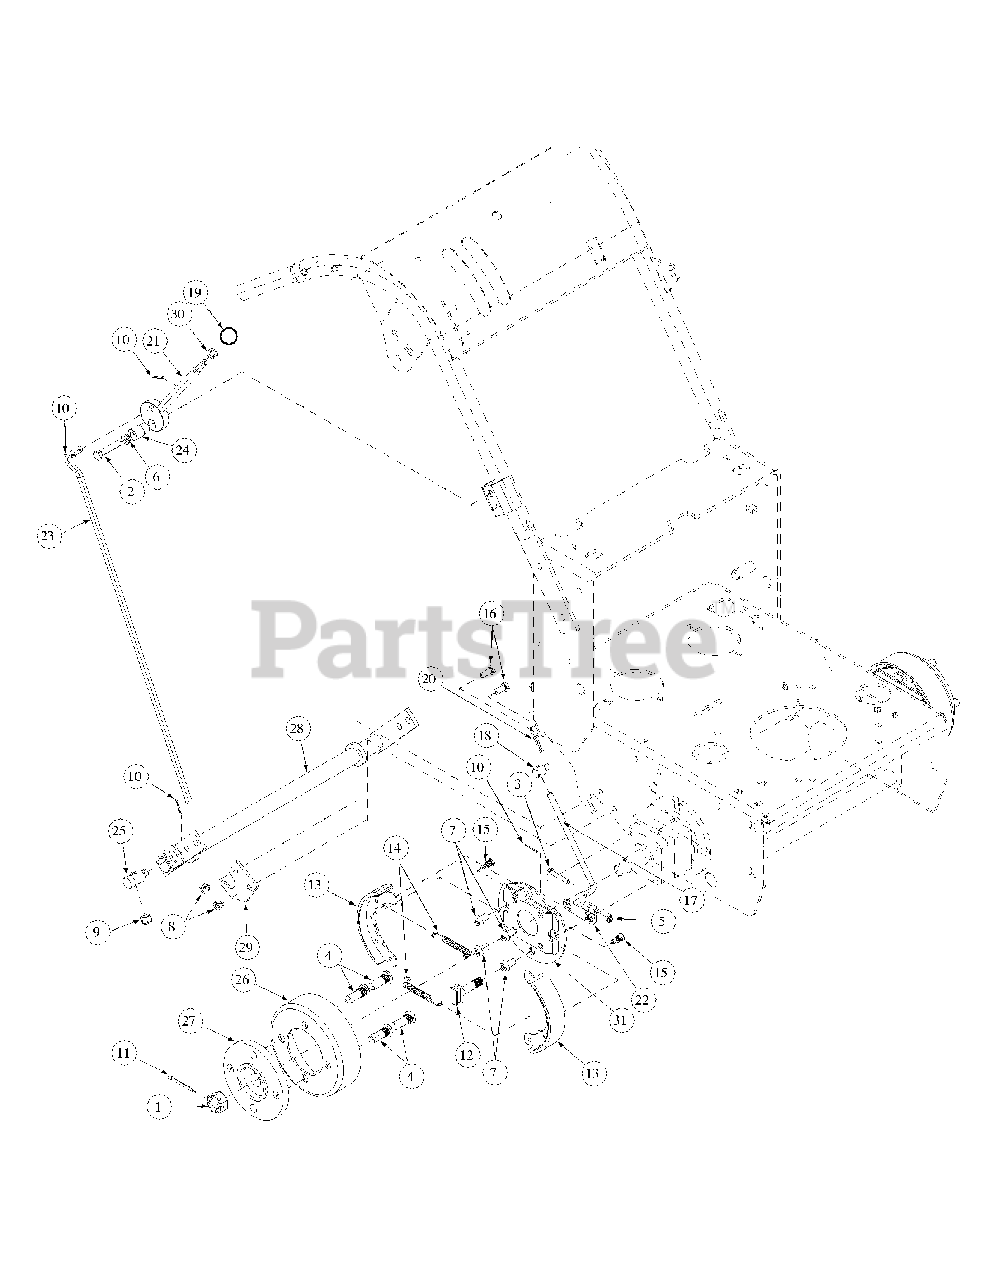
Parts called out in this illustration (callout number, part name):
1	Nut, Castle, 3/4-16
2	Capscrew, 3/8-16 x 1" Grade 5 Zinc
3	Cap Screw, 1/4-20 x 1.50, Grade 5
4	Bolt, Wheel, 1/2-20 x 1-3/8
5	Lock Nut, Nylon Insert, 1/4-20 Grade A
6	Lock Washer, 3/8 Zinc
7	Capscrew, Socket Button Hd., 3/8-16 x 3/4 Zinc
8	Nut, 5/16-18, Nylock
9	Nut, Nylon Insert, 3/8-16 Grade A
10	Cotter Pin, 3/32 x 3/4, Zinc
11	Cotter Pin, 5/32 x 1-1/2 Zinc
12	Brake Cam, Actuating
13	Brake Shoe w/Lining, 6 x 1-1/4
14	Brake Spring, Tension
15	Brake Spring, Anti-Vibration
16	Cap Screw, 5/16-18 x 3/4, Grade 5
17	Brake Rod
18	Swivel Joint
19	Red Knob, Shift w/Insert
20	Hair Pin 3/8"-1/2"
21	Lever Assembly, Brake
22	Brake Clamp, Control Assembly Hydro
23	Rod, Long Brake, Hydro WB
24	Pivot Spacer, Hydro WB
25	Brake Pull Joint
26	Brake Drum
27	Hub, Wheel Motor
28	Brake Pivot Shaft Assembly
29	Pivot Mount, Brake
30	Nut, 3/8-16, Jam, Grade 2
31	Brake Backing Plate
